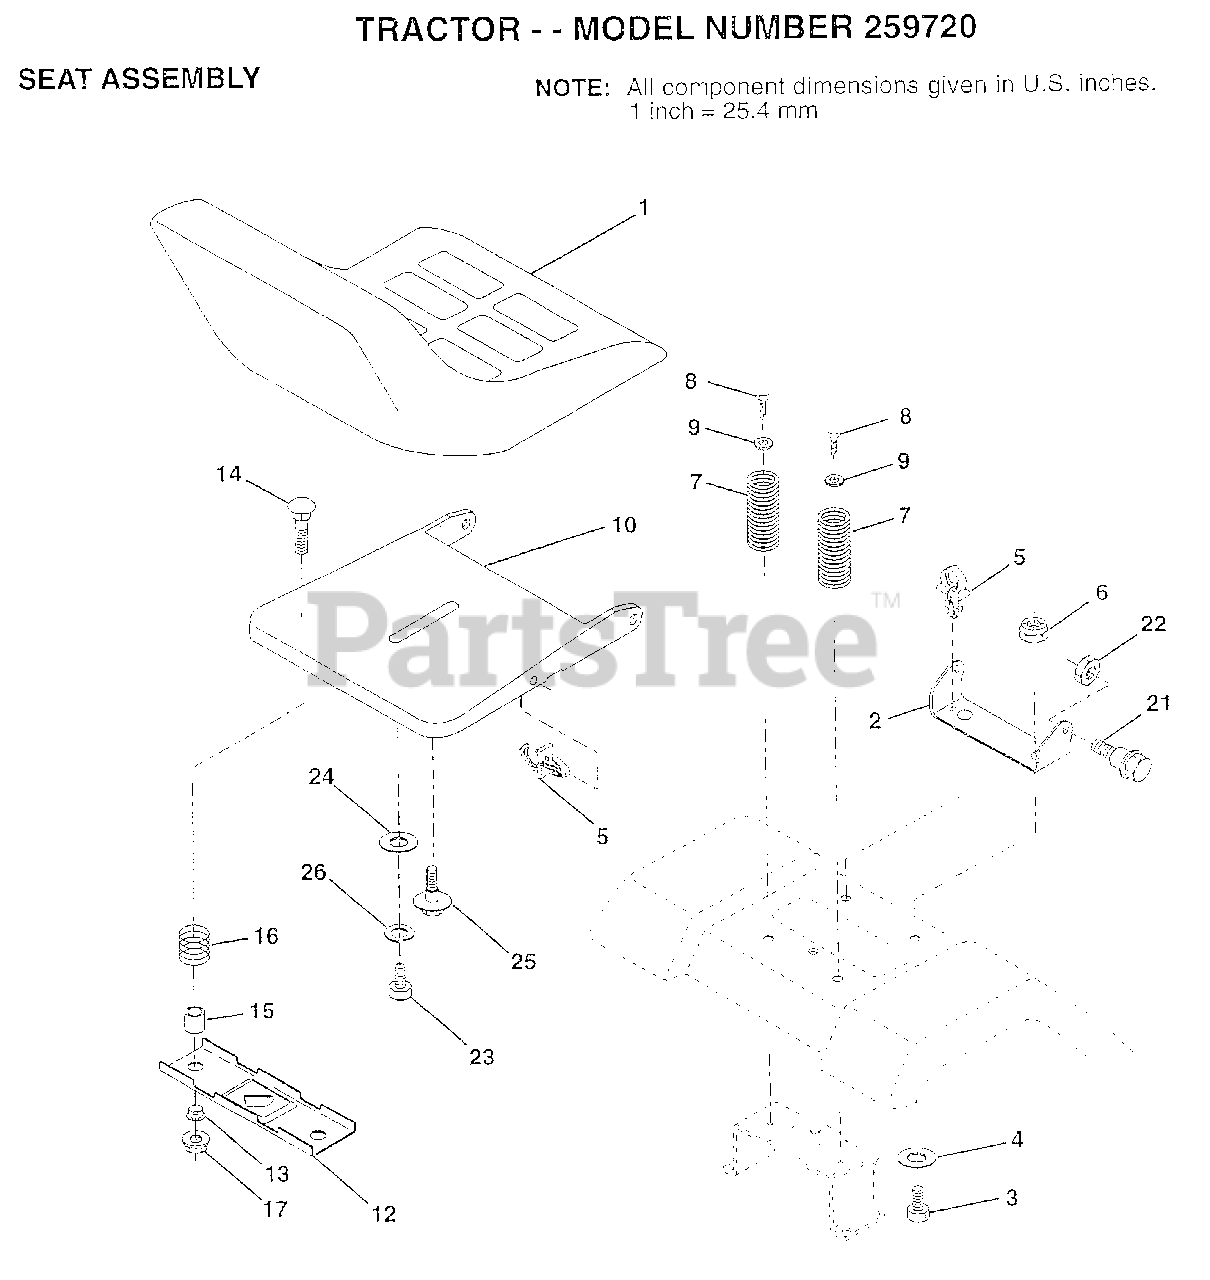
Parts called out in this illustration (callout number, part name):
2	BRACKET PVT SEAT
3	BOLT
4	WASHER PM
5	CLIP.PUSH-IN.HING
6	NUT
7	SPRING COMPRESSIO
8	SCREW GTV
9	WASHER
10	PAN-SEAT
12	BRKT SWITCH
13	BUSHING
14	BOLT-RD HD SQ NK
15	SPLIT SPACER
16	SPRING
21	"BOLT,SHOULDER"
22	NUT
23	BOLT
24	WASHER
25	"BOLT,SHOULDER"
26	LOCKWASHER
